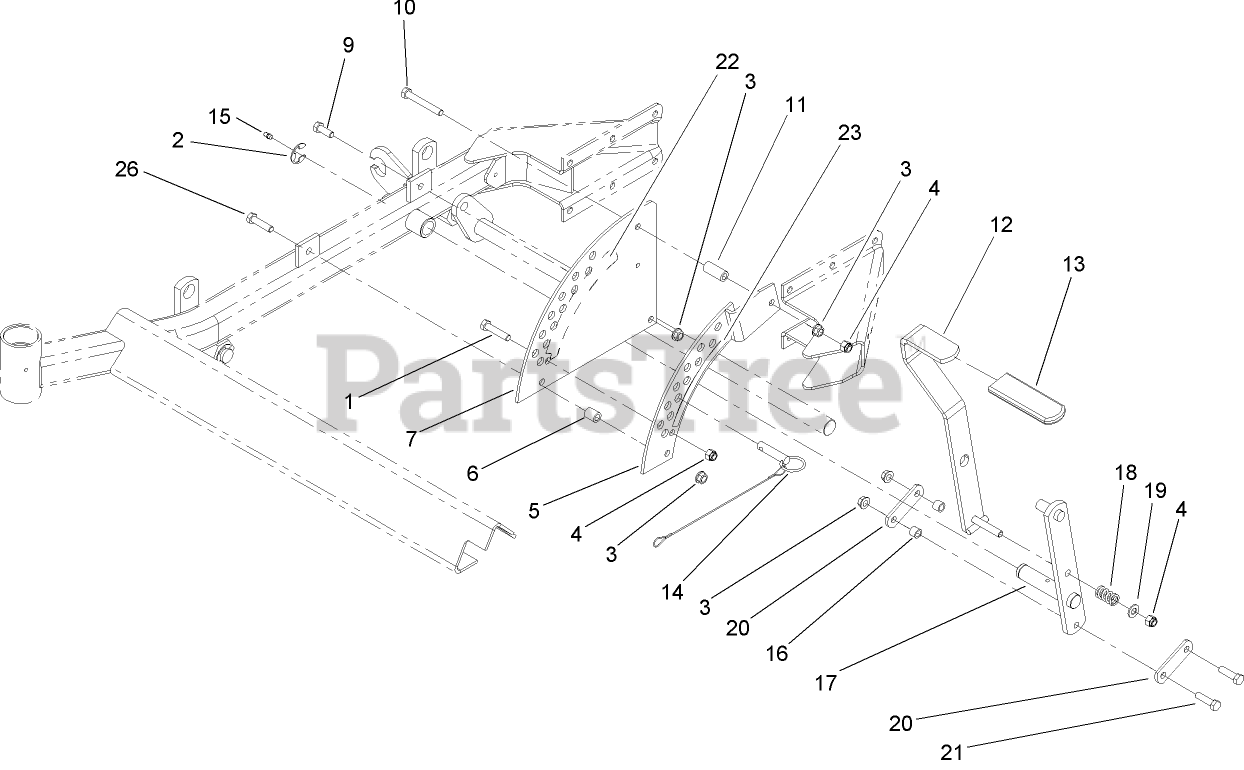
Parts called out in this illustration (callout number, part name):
1	SCREW-HH
2	RING-RETAINING, EXT
3	NUT-HHF, WHIZ
4	NUT-LOCK, NI
5	PLATE-LIFT, DECK
6	BUSHING-LEVER, LIFT
7	PLATE-LIFT, DECK
9	SCREW-HH
10	SCREW-HH
11	BUSHING-LEVER, LIFT
12	HANDLE-LIFT
13	GRIP-LEVER, LIFT
14	Hitch Pin ASM
15	FITTING-GREASE
16	Bushing
17	LIFT ARM ASM
18	SPRING-COMPRESSION
19	WASHER-FLAT
20	ARM-LIFT, DECK
21	SCREW-HH
22	DECAL-DECK HEIGHT, OUTER
23	DECAL-DECK HEIGHT, INNER
26	SCREW-HH
